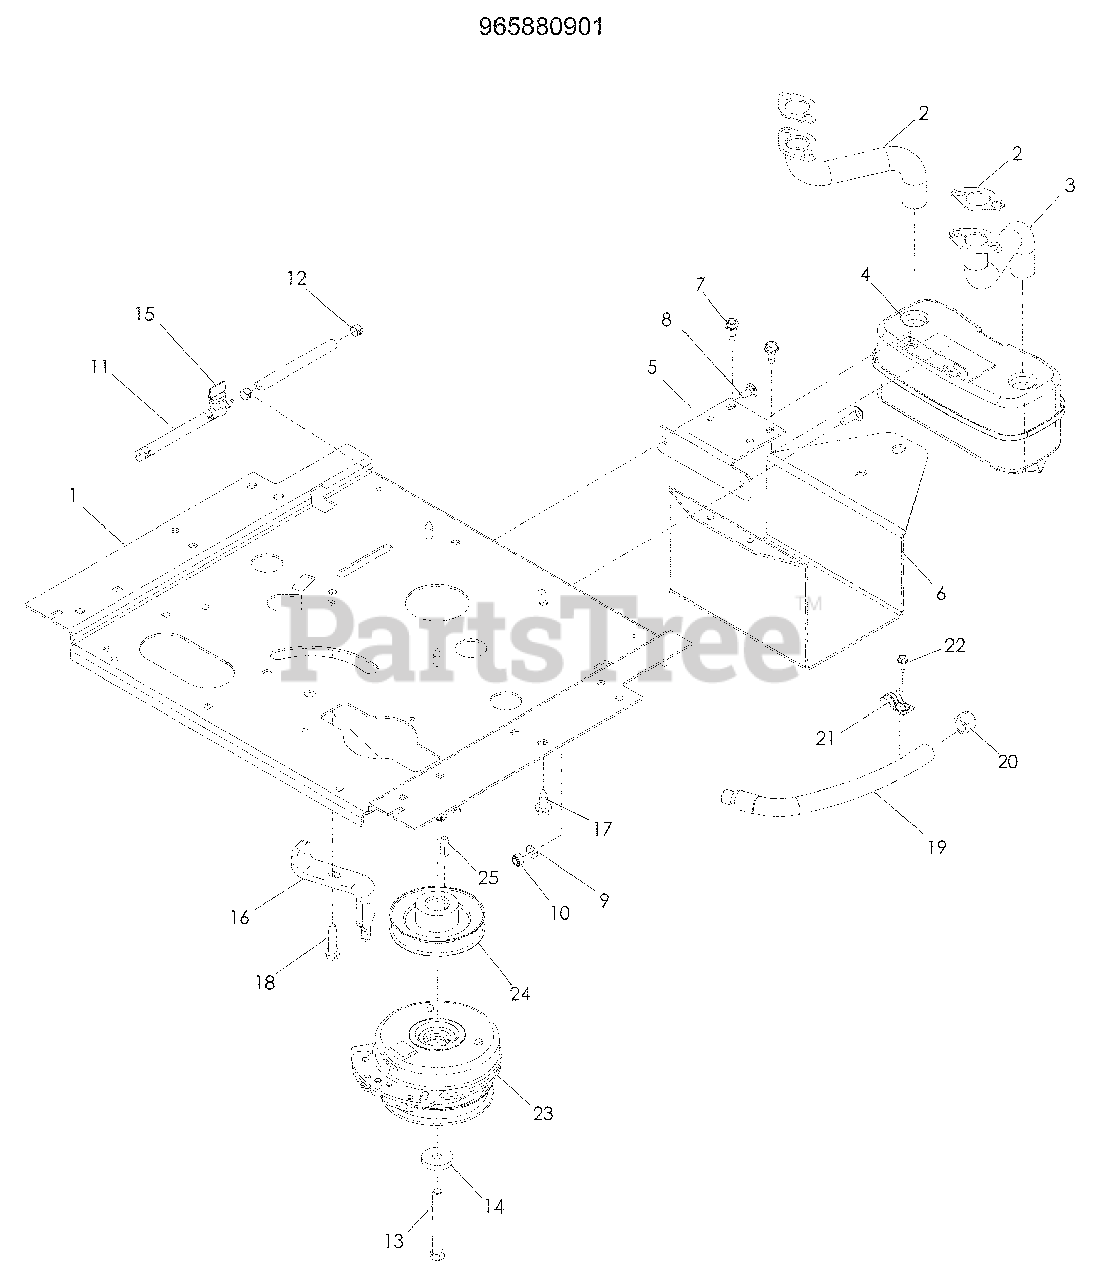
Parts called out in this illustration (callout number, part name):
1	PLATE, ENGINE
2	EXHAUST TUBE, RT
3	EXHAUST TUBE, LT
4	MUFFLER ASM TWIN
5	BRACKET, MUFFLER
6	GUARD, MUFFLER
7	BOLT 5/16-18 x ¾ THD FRM
8	RHSNB 5/16-18 x ¾
9	WASHER 5/16 SAE FLAT
10	NUT 5/16-18 HEX NYLOC
11	FUEL LINE 5"
12	CLAMP, HOSE
13	HCS 7/16-20 x 3½
14	WASHER, CLUTCH
15	VALVE, FUEL
16	STOP, CLUTCH
17	HHFS 3/8-16 x 1 THD FRM
18	BOLT 3/8-16 x 1½ THD FRM
19	HOSE, DRAIN
22	SCREW ¼-20 x 5/8 SLF TAP
23	CLUTCH, 105 FT/LBS
24	PULLEY, DRIVE
25	KEY ¼ SQ x 1
26	WASHER 7/16 SLW
27	GASKET, EXHAUST
